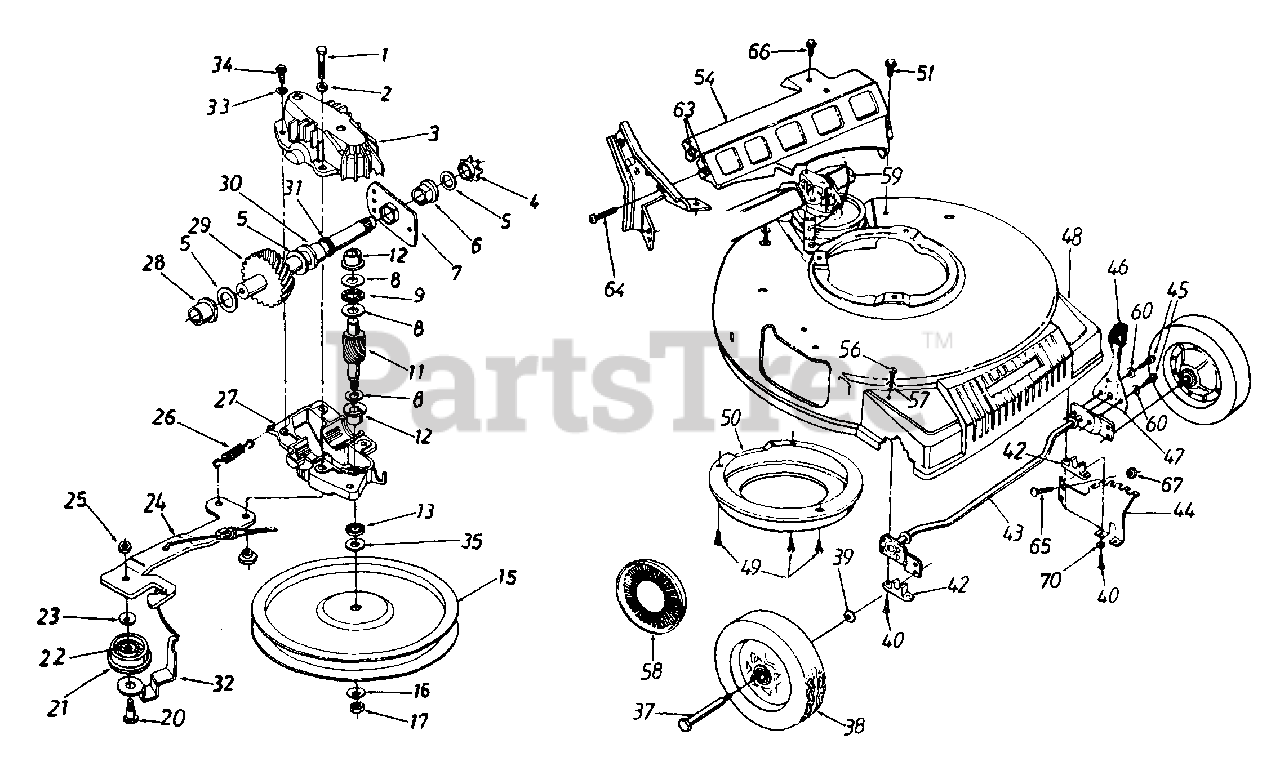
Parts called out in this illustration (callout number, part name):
1	Hex Patch Bolt 1/4-20 x 1.25"
2	L-Wash. 1/4" I.D.
3	Upper Hsg. Half
4	#48 Sprocket 7 T x 1/2 Pitch
5	Fl-Wash. 5/8" I.D. x .030
6	Hex Flange Brg. .631" I.D.
8	Thrust Wash. .382" I.D. x .70" O.D.
9	Thrust Bearing .375" I.D. x .812" O.D.
11	11 Tooth Pinion Shaft
12	Flange Bearing
13	Oil Scalp
15	Fl-Pulley 5.06" O.D.
16	Bell-Wash. .265" I.D. x.75"
17	Hex L-Nut 1/4-28 L.H. Thd.
20	Shld. Bolt .375" Dia. x .40"
21	Fl-Idler Plastic 1.50" Dia.
22	Needle Brg. .375" x .31
23	Bell-Wash. .265" I.D.
24	Idler Brk't. Ass'y.
25	Hex Patch L-Nut 1/4-28 Thd.
26	Extension Spring 1.12" Lg.
27	Lower Hsg. Half
28	Flange Bearing .566 Dia.
29	Shaft Ass'y.
30	Flange Bearing .629 Dia.
31	Oil Seal .625 Dia.
32	Belt Keeper
33	L-Wash. #10 I.D.
34	Hex B-Tap Scr. #10 x .62"
35	Hex Washer .26" x .88"
37	Front Axle Bolt
38	Wheel Ass'y. Comp. 8 x 2"
39	Bell-Wash. .380" I.D. x.88
40	Hex Wash. Hd. Scr. 1/4 x 1" Lg.
42	Block Bushing
45	Hex TT-Tap Scr. 1/4-20 x .38"
46	Knob
47	Spring Lever
48	Plastic Front End
49	Hex B-Tap Scr. 1/4" x .38"
57	Bell-Wash. .345" I.D. x .88"
58	Hub Cap
59	S.P. Cable
60	External L-Wash. 1/4" I.D.
63	Speed Nut #10-24 Thd.
64	Hex Tap Scr. #10-16 x .5" Lg.
65	Carr. Bolt 1/4-20 x .5" Lg.
66	Hex B-Tap Scr. 5/16-18 x .5"
67	Hex Flange L-Nut 1/4-20 Thd.
70	L-Wash. 1/4" I.D.
